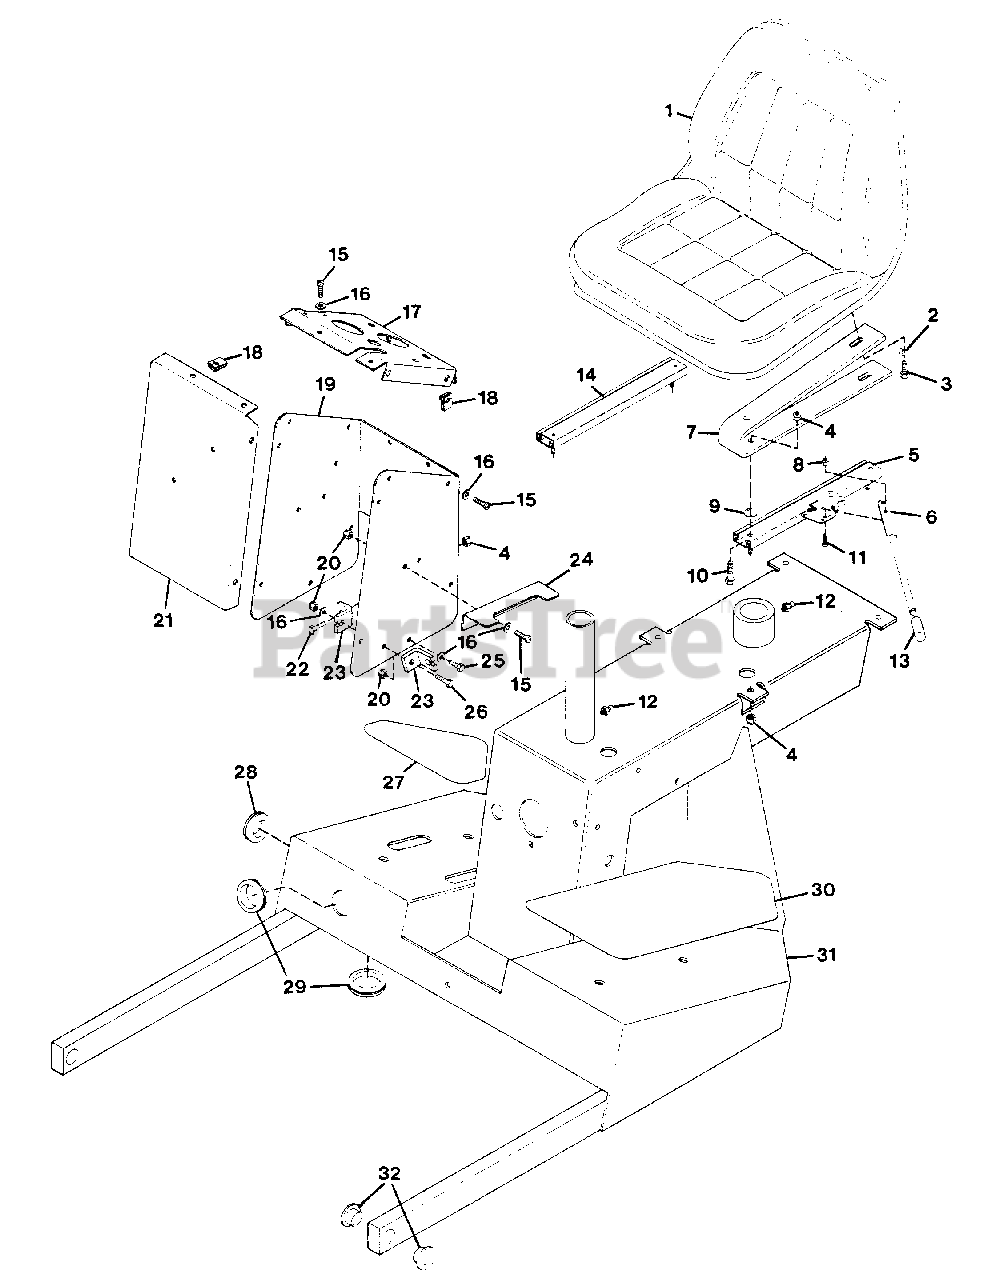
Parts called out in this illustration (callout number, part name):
1	SEAT, HIGH BACK
2	WASHER, LOCK 5/16
3	BOLT, HEX 5/16-18X.75
4	NUT, LOCK 5/16-18
5	ADJUSTER, SEAT W/LATCH
6	HANDLE, SEAT SLIDE
7	SPRING, SEAT
8	NUT, LOCK 10-24
9	SPACER
10	BOLT, HEX 5/16-18X1.25
11	SCREW, MACHINE 10-24X.625 PHD
12	FITTING, LUBE 1/4-28
13	TIP, LEVER
14	ADJUSTER, SEAT
15	SCREW, MACHINE 1/4-20 PAN HD
16	WASHER, FLAT .281X.625X.065
17	SILK SCREEN, CONTROL PANEL
18	NUT, RETAINER
19	SUPPORT, PANEL
20	NUT, LOCK 1/4-20
21	PANEL, SILK SCREEN COVER
22	BOLT, HEX 5/16-18X.875
23	BRACKET, CABLE
24	SILK SCREEN, BRAKE STOP
25	BOLT, HEX 1/4-20X.625
26	BOLT, HEX 1/4-20X.875
27	COVER, FOOTBOARD L.H.
28	GROMMET
29	GROMMET
30	COVER, FOOTBOARD R.H.
31	WELDMENT, FRAME REAR
32	BUSHING, NYLON .76X1.00X.6 FLG.
NS	KIT, ARM REST
NS	DECAL, 18-H
NS	DECAL, 20-H
NS	DECAL, SAFETY
